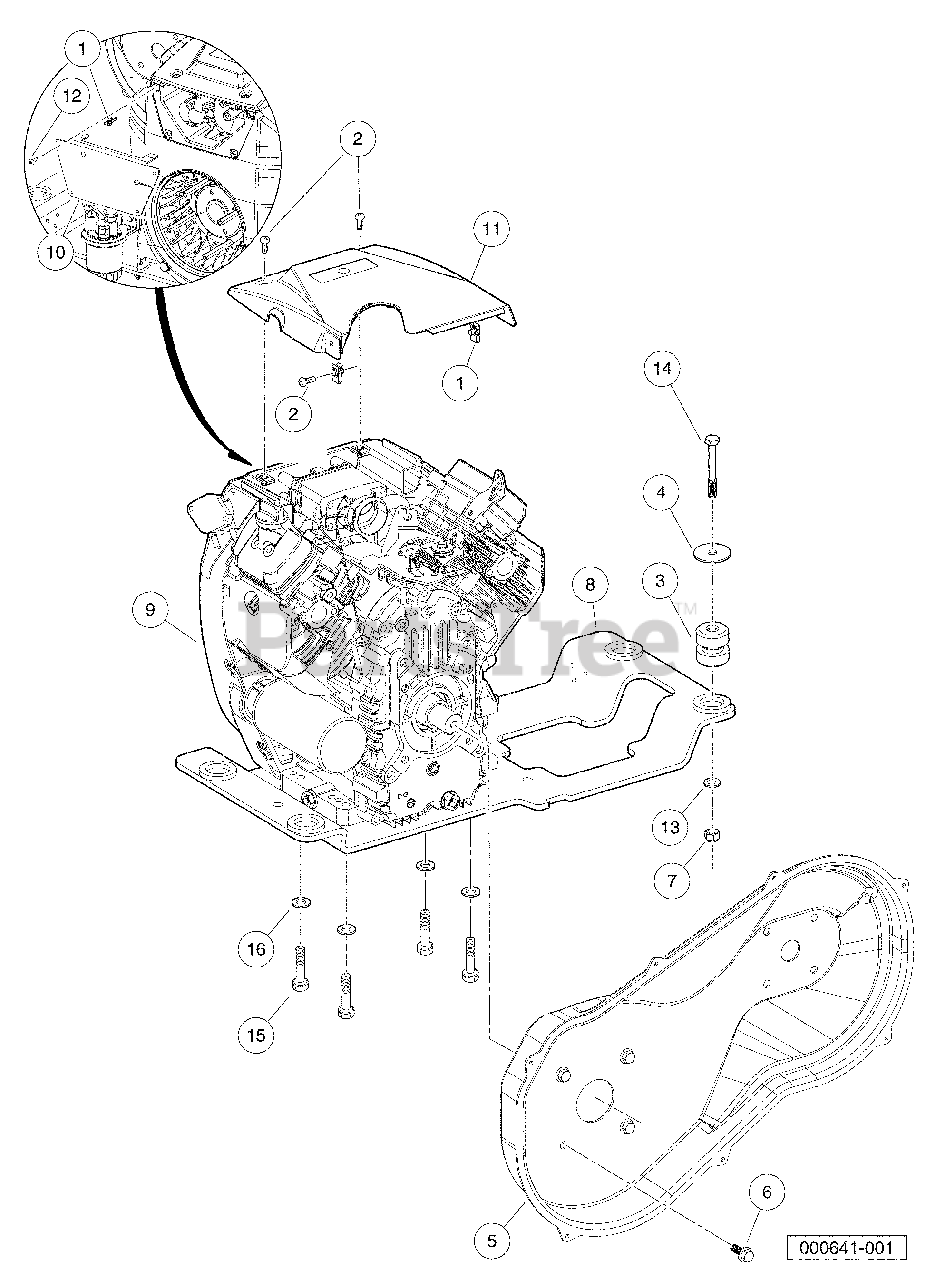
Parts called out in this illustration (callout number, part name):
1	U-nut, M6-1.0 Prev Torque
2	Screw, M6 Torx Bttn Hd Sems
3	Isolator Ring and Bushing
4	Washer, Snubbing, Ring N Bush
5	Cover, CVT Inner, FH680D
6	Bolt Flanged Head, 3/8-16x1.0 with Loctite
7	Locknut, M12x1.75 Nylon Insert.
8	Weldment, Eng Mnt, Kaw, Fh680d
9	Engine, Kawasaki, FH680D
10	Engine, Front Cover, Fh680d
11	Cover, Engine, Top
12	Screw, Pn Hd Blk, 10-16 X .625
13	Washer, M12 Hard
14	Bolt, M12 X 1.75 X 90
15	Bolt, M10 X 1.5 X 60
16	Washer, M10 Hard
